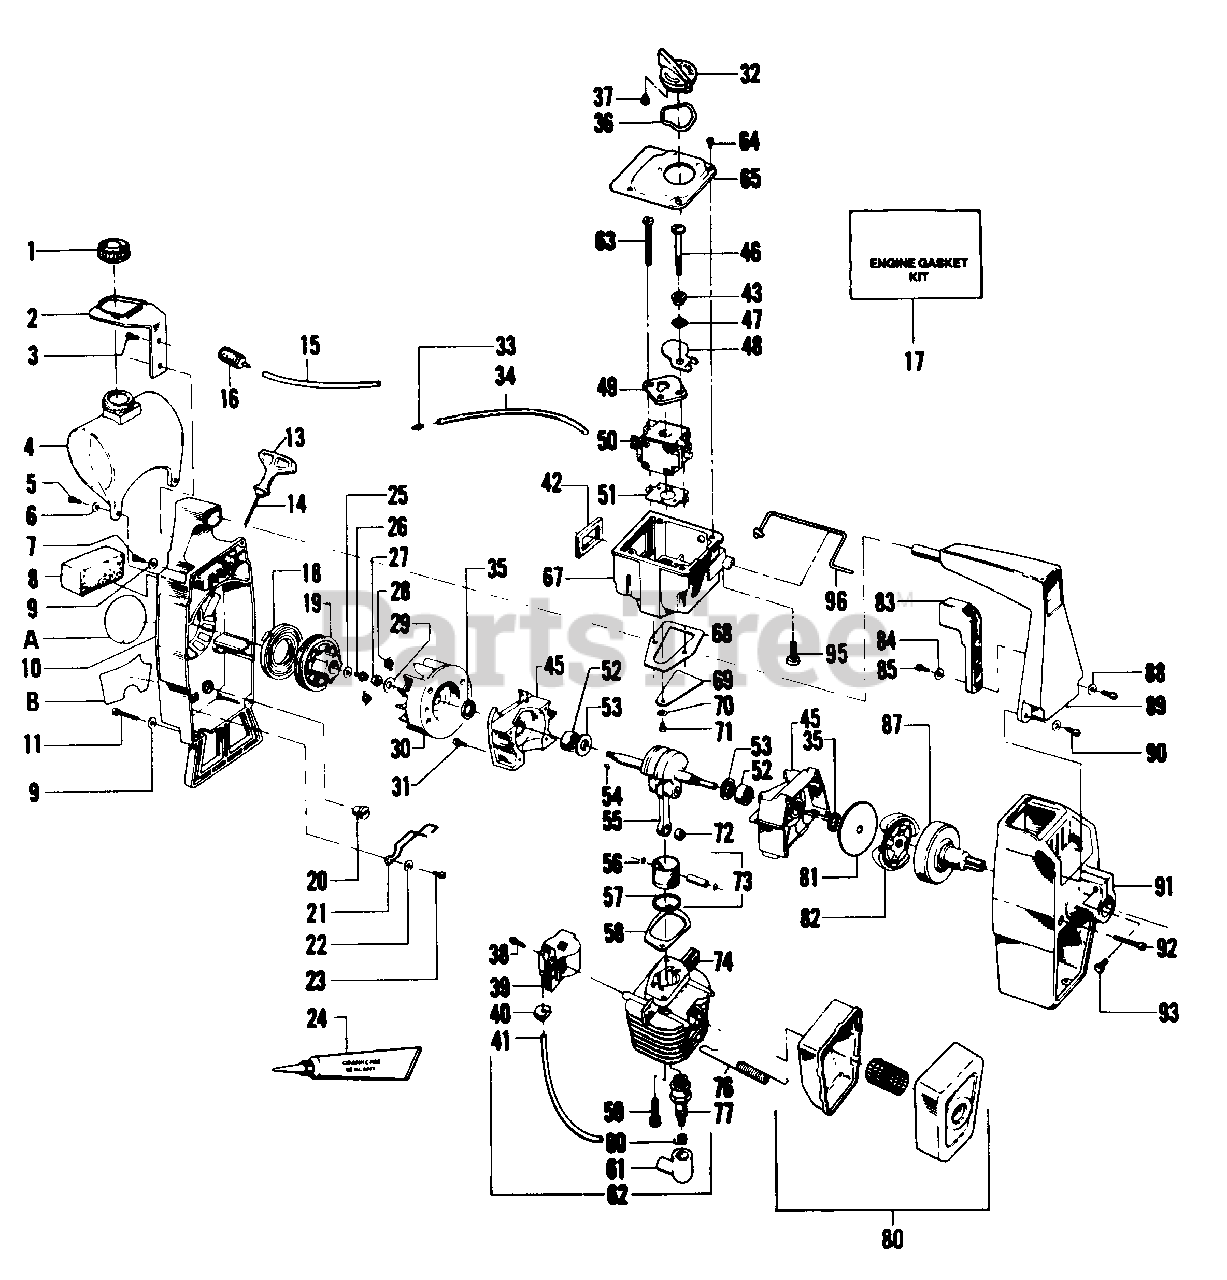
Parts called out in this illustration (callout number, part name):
1	Fuel Cap Assembly (Inc. O-Ring)
2	Bracket-Fuel Line
3	Screw-Bracket Handle (#1/4-10x1-1/8")
4	Fuel Tank Ass'y. (Inc. #1, 15 & 16)
5	Screw-Fuel Tank Fan Hsg. (#10x1")
6	Washer-Fuel Tank Fan Hsg. #10
7	Screw-Fan Hsg. Top #10-24x5/8" Fil. hd.
8	Air Filter
9	Washer-Flat-#10-Fan hsg.
10	Fan Housing Ass'y.
11	Screw-Fan Housing-Bottom #10-24x1-3/16" Fil.
13	Starter-Handle
14	Rope Kit
15	Line Kit
16	Fuel Pick-Up Ass'y.
17	Engine Gasket Kit (Inc.35,42,51,58,68)
18	Starter-Recoil Spring
19	Starter-Pulley
20	Button-Kill Switch
21	Spring-Kill Switch
22	Washer-Kill Switch
23	Screw-Kill Switch (#8-16x3/8")
24	Crankcase Sealant-3 oz. tube (Optional)
25	Washer-Starter Pulley
26	Screw-Starter Pulley (#10-24x3/4" Hex Hd.)
27	Nut-Flywheel
28	Spring-Starter Dog
29	Washer-Flywheel
30	Flywheel-Ass'y. (Inc. #28)
31	Screw-Crankcase (#10-24x5/8" Fil.)
32	Choke Knob
33	Fitting-Fuel Line
34	Fuel Line-Carburetor
35	Seal-Crankshaft
36	Wave Washer
38	Screw-Ignition Module (#8-32x3/4" Sems)
39	Ignition Module Kit (Inc. 21)
40	Grommet-Plug Wire
41	Lead Wire-High Tension
42	Seal-Carburetor Case
45	Crankcase Ass'y. (Inc. #35, 52 and Qty 4 of 31)
46	Screw-Carburetor
47	Wave Washer
48	Shutter-Choke
49	Plate-Guide, Choke Wire
50	Carburetor-WA-149
51	Gasket-Carburetor
52	Bearing-Crankshaft
53	Thrust Washer-Crankshaft
54	Key-Flywheel
55	Crankshaft & Rod Assembly
56	Retainer-Wrist Pin
57	Piston Ring
58	Gasket-Cylinder
59	Screw-Cylinder (#1/4-20x3/4" Soc. Hd.)
60	Connector-Spark Plug
61	Boot-Spark plug
62	BEVEL GEAR COMPLETE
63	Screw-Carburetor
64	Screw-Carburetor Cover (#8-18x9/16")
65	Cover-Carburetor Case
67	Carburetor Case Ass'y.
68	Gasket-Carburetor Case Crankcase
69	Reed Valve
70	Washer-Reed Valve
71	Screw-Reed Valve (#6-19x5/16")
72	Bearing-Wrist Pin
73	Piston Kit (Inc. 56, 57, & Pin)
74	Cylinder
76	Spring-Muffler Attachment
77	Spark Plug (CJ-14)
80	Muffler Ass'y.
81	Kit-Washer-Clutch
82	Kit-Clutch-Assembly (Inc. Washer)
83	Trigger-Throttle
84	Washer-Throttle
85	Screw-Throttle (#8-16x3/8")
87	Drum and Coupling Assembly
88	Washer-Flat-#10 Shroud
90	Screw-Shroud (Top)-#10-24x7/8"
92	Screw-Shroud (Bottom)-#10-24x1-1/2" Fil.
96	Throttle Wire
A	Decal-Starting Instructions
B	Decal-Choke/OFF
